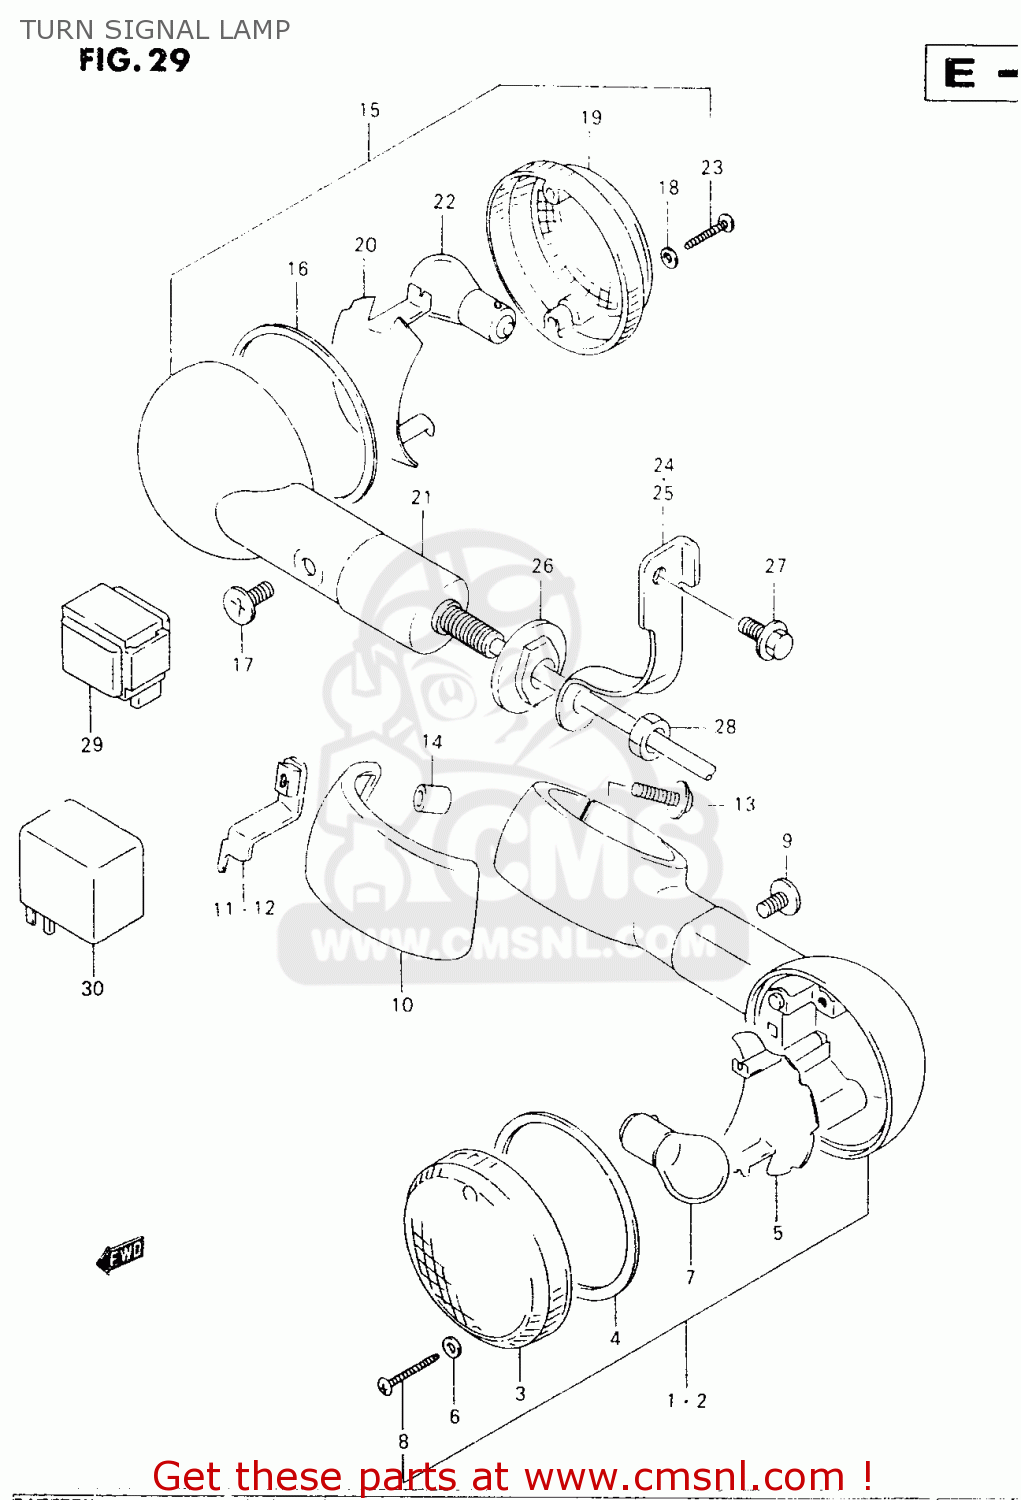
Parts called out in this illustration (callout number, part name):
1	LAMP ASSY,FR TURN SIGNAL,R
2	LAMP ASSY,FR TURN SIGNAL,L
3	LENS
4	GASKET (NAS)
5	REFLECTOR
6	GASKET (NAS)
7	BULB(12V21W)
8	SCREW
9	SCREW
10	COVER,FR TURNSIGNAL STAY
11	BRACKET,FR TURNSIGNAL,R
12	BRACKET,FR TURNSIGNAL,L
13	SCREW(6X25)
14	SPACER(6.4X9.2X12)
15	LAMP ASSY,RR TURNSIGNAL,R
16	GASKET (NAS)
17	SCREW
18	GASKET (NAS)
19	LENS
20	REFLECTOR
21	STAY,TURNSIGNAL RR
22	BULB(12V21W)
23	SCREW
24	REINF,RR TURNSIGNAL,R
25	REINF,RR TURNSIGNAL,L
26	SPACER,RR TURNSIGNAL
27	BOLT
28	NUT
29	RELAY ASSY
30	RELAY ASSY,TURNSIGNAL LAMP
